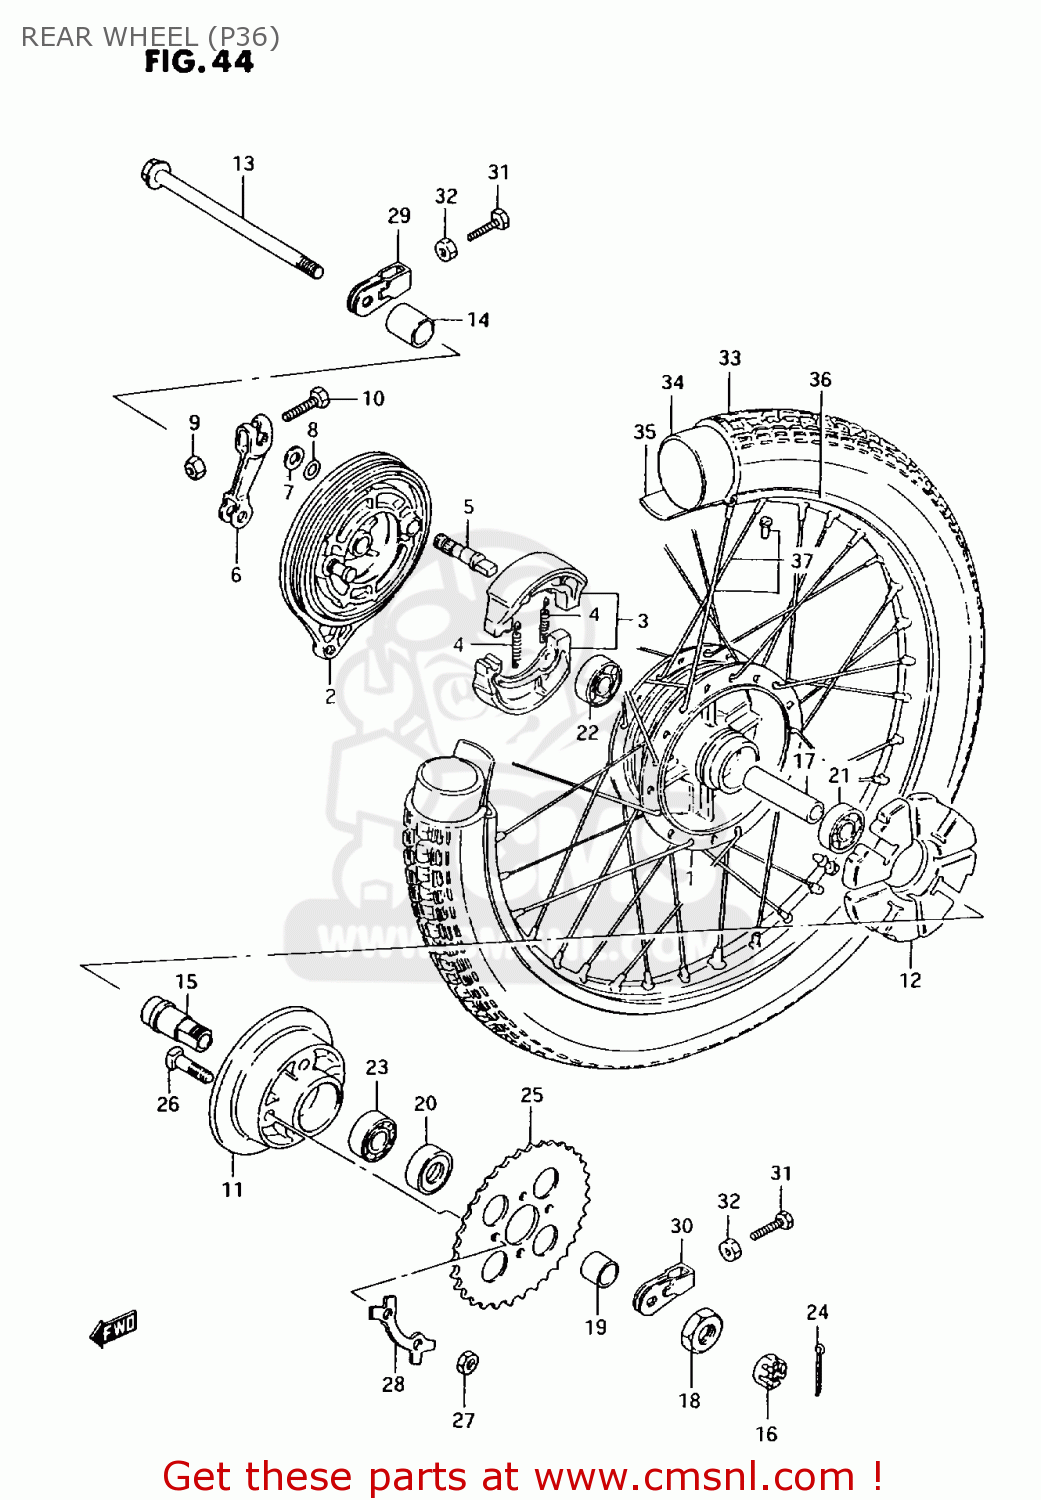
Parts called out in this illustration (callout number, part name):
1	HUB,RR WHEEL
2	PANEL,RR BRAKE ANCHOR
3	SHOE & SPRING SET,BRAKE (NAS)
4	SPRING
5	CAM,BRAKE
6	LEVER,RR BRAKE CAM
7	WASHER (14.5X22X1.6)
8	O-RING (D:2.4 ID:13.8)
9	NUT
10	BOLT(6X32)
11	DRUM,RR SPROCKET MOUNTING
12	ABSORBER,RR WHEEL HUB SHOCK
13	AXLE,RR
14	SPACER(12.2X22X39)
15	SHAFT,RR SPROCKET DRUM
16	NUT
17	SPACER (12.6X19X58)
18	NUT
19	SPACER(17X25X25)
20	SEAL,OIL(25X40X6)
21	BEARING
22	BEARING
23	BEARING
24	PIN 20X20
25	SPROCKET, REAR (NT:42)
26	BOLT(8X33.5)
27	NUT
28	WASHER
29	ADJUSTER,CHAIN
30	ADJUSTER,CHAIN
31	BOLT(8X50)
32	NUT
33	TIRE,RR(2.75-18 42P)
34	TUBE,INNER
35	PROTECTOR,INNER TUBE
36	RIM,FR WHEEL 1.60X18
37	SPOKE SET,RR
